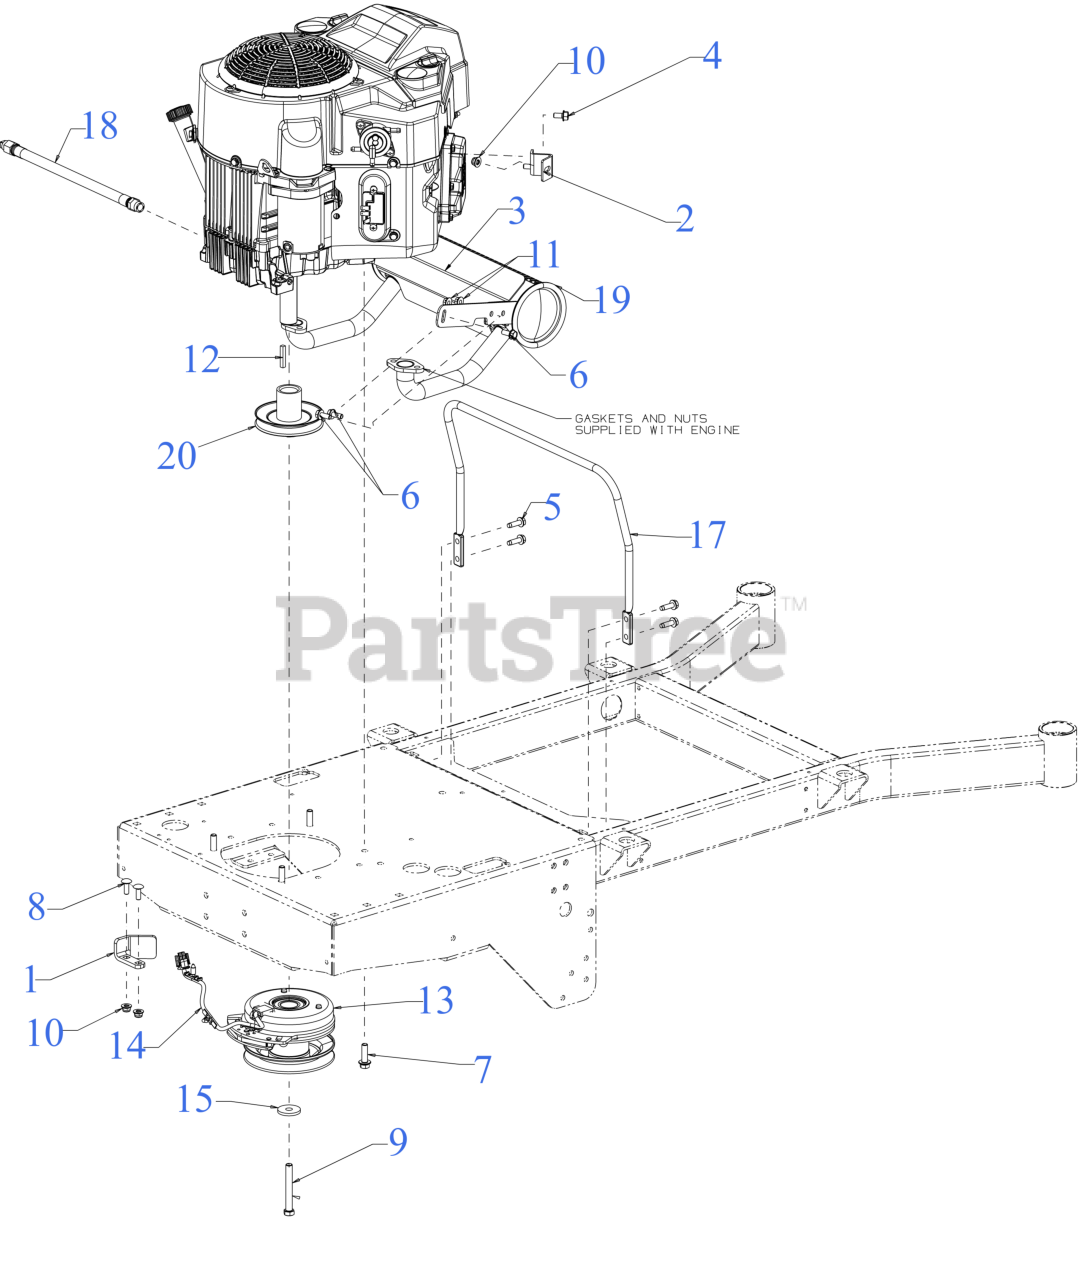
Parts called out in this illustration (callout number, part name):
2	MUFFLER MOUNTING BRACKET
3	MUFFLER SHIELD
4	SCREW M8 x 1.25 x 16MM GR8.8
5	SCREW 5/16-18 x 1.00
6	SCREW 5/16-18 x .750 GR8
7	SCREW 3/8-16 x 1.25 GR5
8	BOLT 5/16-18X .875 GR1
9	SCREW 7/16-20 x 3.25 GR5
10	FLANGE LOCK NUT 5/16-18
11	FLANGE NUT
11	HEX FLANGE NUT
12	SQUARE KEY 1/4 x 1.50
13	PTO CLUTCH
14	CLUTCH HARNESS 11"
15	FLAT WASHER .45 x 1.5 x .172 HT
17	MUFFLER ROD
18	OIL DRAIN HOSE
19	MUFFLER (ROUND)
20	ENGINE PULLEY (1.125")
